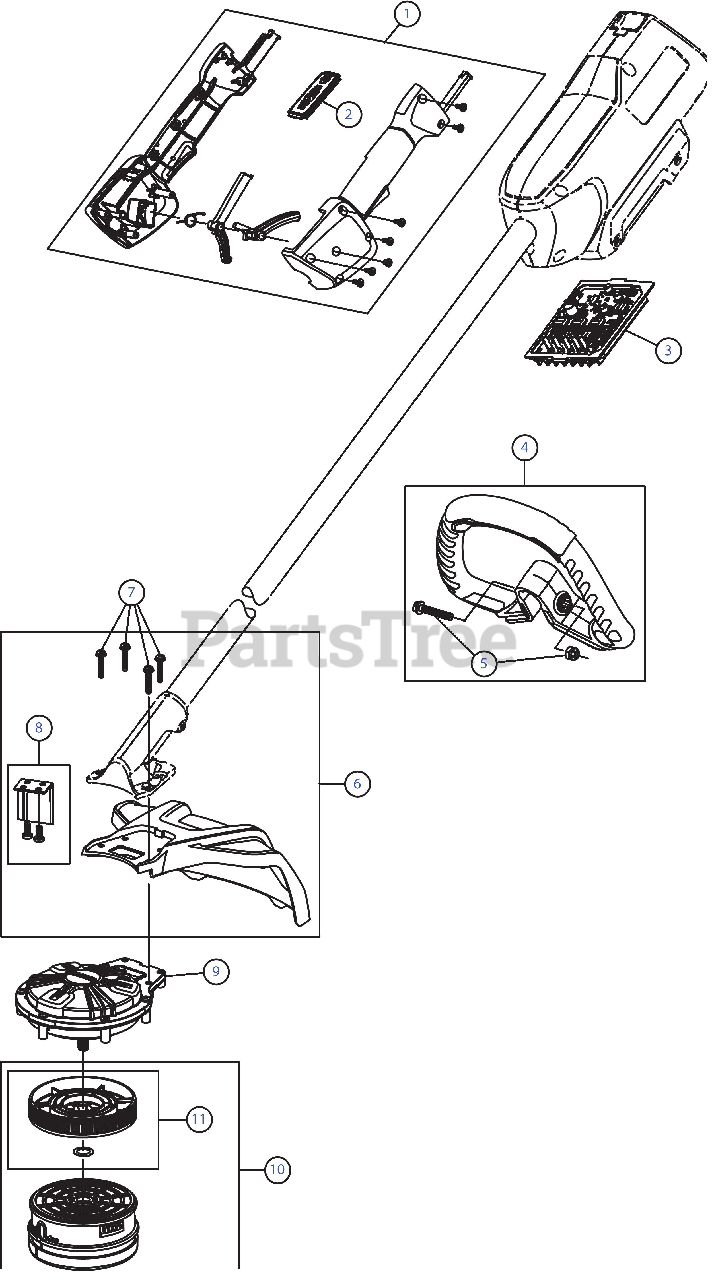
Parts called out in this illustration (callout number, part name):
1	Elite Grip Handle Assembly
2	Operator Panel Assembly
3	Elite Controller PCB Assembly
4	D-Handle Assembly
5	D-Handle Hardware
6	Elite Shield Assembly
8	Blade Assembly
8	Elite Motor Assembly
10	Elite Cutting Head Assembly
11	Elite Weed Wrap Cover
